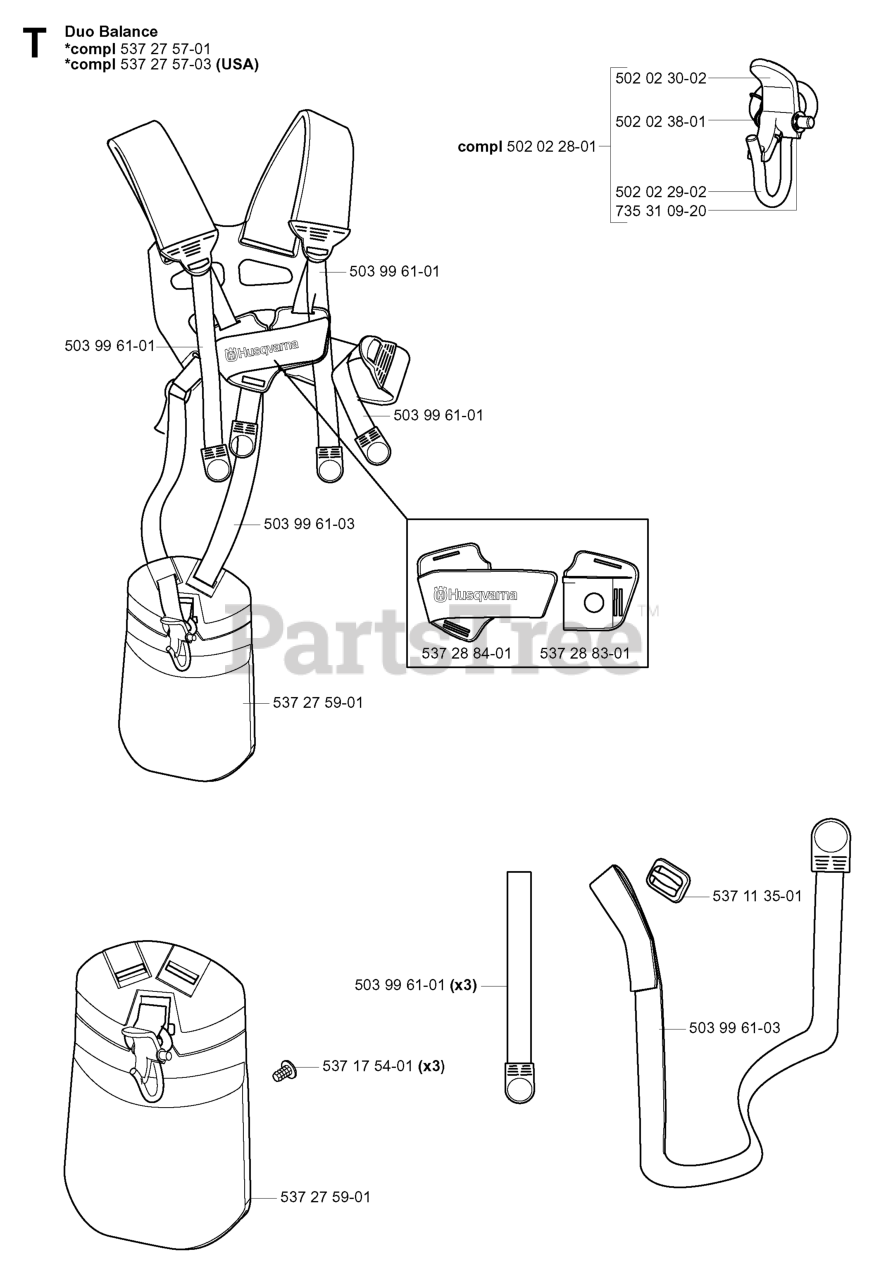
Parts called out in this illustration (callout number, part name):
1	CYLINDER.HEAD.ASSY(SK2911000)
2	PUSH ROD TAPPET KIT
3	VALVE.COVER.LCT.414CC.
5	PISTON.AND.ROD.ASSY(SK2911400)
6	CONNECTING ROD ASSY SNO.LCT
7	CAMSHAFT.LCT.291CC
8	FLYWHEEL.EL.ST.SKSNO2401.1
9	FLYWHEEL.FAN
10	CRANKSHAFT LCT.SKSN2805.1
13	MUFFLER ASSY LCT SNO
14	FUEL TANK ASSY - SNOW (291CC)
15	FUEL.PETCOCK.SNOW(SKSN4900)
16	FUEL.TANK.CAP.SNOW(SKSN4301)
17	CARBURETTOR LCT
18	COIL.IGN.CDI.SKSN2403.1
20	SPARK.PLUG(SK2911550)
21	ON/OFF.SWITCH.SNOW(SKSN4403)
23	FUEL HOSE KIT
24	TOP.SHIELD.LCT.
25	GOVERNOR.GEAR.ASSY(SK2912900)
26	GOVERNOR.ARM.ASSY.(SKSN2502)
27	GOVERNOR.SHAFT.(SK2913100)
28	STARTER RECOIL.291/306CC.LCT
29	STARTER.CUP.SMALLSNOW(SKSN2601
30	BLOWER HOUSING.LCT.291/306CC W
31	CRANKCASE.COVER.ASY(SK2913600)
32	OIL.SEAL.KIT(SK2913900)
33	SWITCHBOX BRACKET ES LCT 291 S
34	SPARK.PLUG.BOOT.SNW,SKSN4691.1
35	ELECTRIC.START.ASSY(SKSN2400.2
36	ENGINE.GASKET.KIT(SK2914300)
37	DIPSTK.OIL.BLK.LCTSK4143711.1
38	ROCKER ARM KIT
39	CHOKE.KNOW.SNOW(SKSN4500)
40	NONREMVABLE.OIL.PLUG(SK4143715
43	TUBE.BREATHER.LCT.219CC/414CC
47	HIGHOIL.FILL.ASSY.KIT(SKSN4911
48	WIRE.HARNESS(SKSN4406)
49	OIL.DRAIN.PLUG
50	HEATER.BOX.ASSY.SNOW(SKSN2100)
51	SHIELD.CYLINDER.SNOW(SK4141010
52	PRIMER.BULB.ASSY(SKSN4304)
53	KEY.SWITCH.ASSY.SNOW(SKSN4401)
54	KEY SET(2 KEYS) SKSN0407.1
55	OIL PIPE DRAIN EXTENDED.LCT SK
56	SHIELD.VAPOR(SKSN4606)
57	MUFFLER GUARD.CE.LCT
58	GOVERNOR.LINK.SHIELD(SKSN2501)
59	FUEL TANK SKIRT.LCT.291/306CC
60	ALTERN.60WATT.SKSN2402.1
61	FUEL KNOB-SNOW
62	HANDLE.RECOIL.DELUXE.LCT
65	TAPPET KIT.LCT.SK2911005.1
69	STUD.CARB.MOUTING.KIT.291CC
70	CARBURETTOR REPAIR KIT 291CC/4
77	BOLT.KIT.RECOIL.LCT.ALL.ENGINE
81	KEYS.FLYWHEEL.136/291CC.5PACK
82	SPACER.CARBURETOR.291CC.LCT
85	STRAINER.FUEL.TANK.LCT.208CC
86	KIT.BOLT.CYLINDER.HEAD.(4PC)
87	KIT.7-BOLT.CRANKCASE.CVR.291CC
88	STUD.MUFFLER.KIT.LCT
89	KNOB LCT.SKSN5325.1 SPEED
91	GASKET KIT CRANKSHAFT.LCT
92	CENTER VALVE COVER BOLT
9999	KIT.BOLT.LCT.SK9990.1
9999	HIGH.ALTITUDE.JET.6000FT ANDUP
